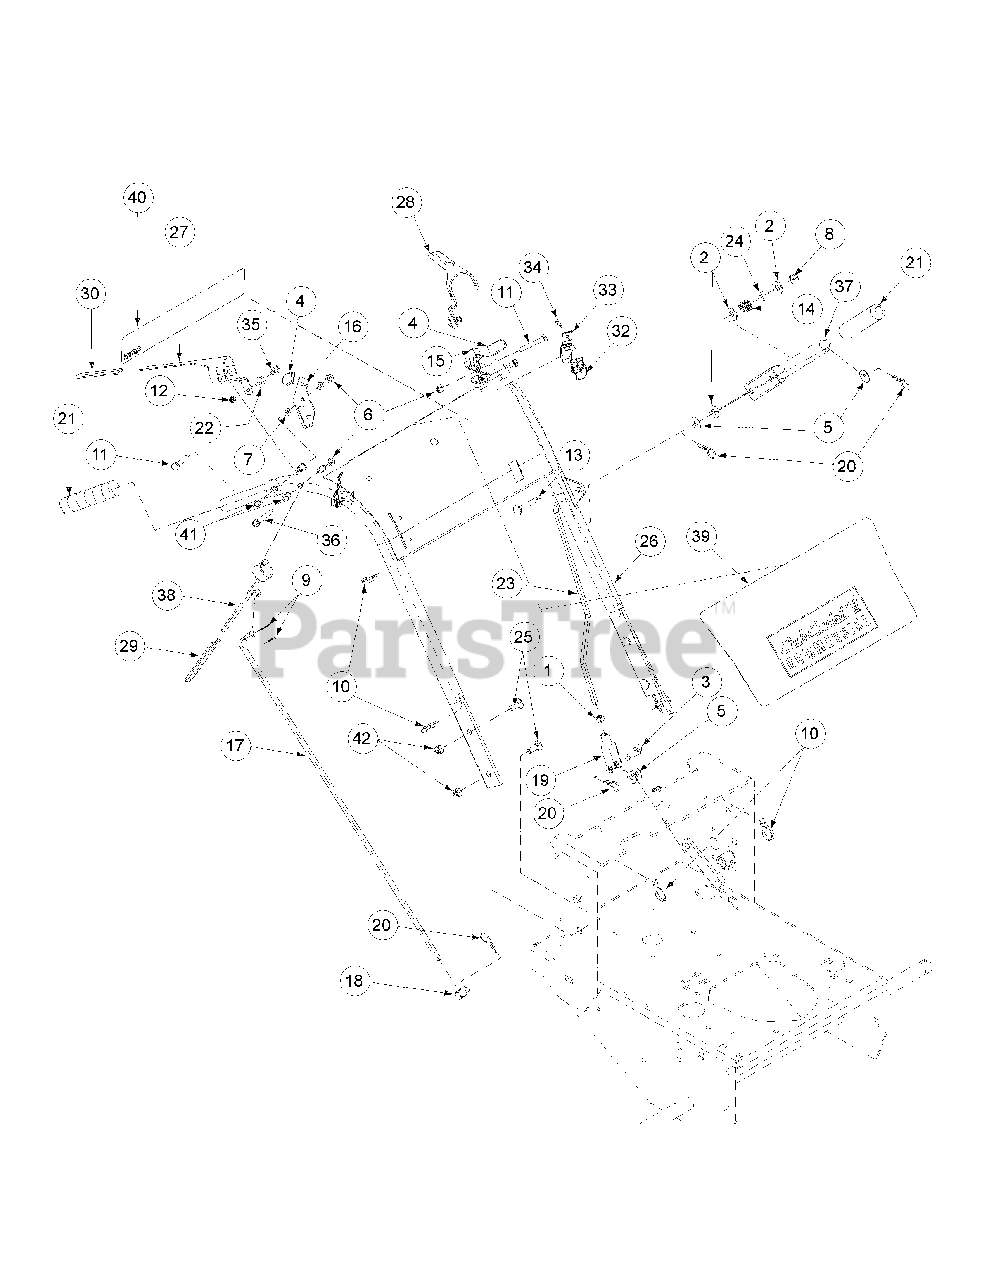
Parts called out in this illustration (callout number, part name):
1	Hex Nut, 3/8-16
2	Flat Washer, 3/8 Zinc
3	Clevis Pin, 3/8 x 1-1/8 Zinc
4	Grip, Neutral Latch, 1.25"
5	Flat Washer, 3/8 Zinc
6	Nylock Nut, 5/16-18
7	Flat Washer, 5/16 Zinc
8	Lock Nut, Nylon Insert, 3/8-16
9	Cotter Pin, 3/32 x 3/4, Zinc
10	Cable Tie, 3/16 x .05 x 7.4
11	Hex Cap Screw, 5/16-18 x 2
12	Lock Nut, Nylon Insert
13	Carriage Bolt, 3/8-16 x 2
14	Spring, .850 OD x 1
15	Neutral Latch, Left Hand
16	Neutral Latch, Right Hand
17	Steering Control Rod
18	Joint Swivel
19	Yoke, 3/8-16 Female
20	Hair Pin 3/8-1/2
21	Handle Grip, Black, 1"
22	Control Rod, Hydro Spacer
23	Blade Clutch Rod
24	Spring Sleeve
25	Carriage Bolt, 3/8-16 x 1.25
26	Handle Assembly
27	Operator Presence Control RH
28	Operator Presence Control LH
29	Control Sleeve, Black
30	Operator Control Sleeve, Yellow
32	Switch Mounting Snap
33	Operator Presence Return Spring
34	Hex Index Washer Screw, 0.500
35	Shoulder Screw, .38 x .412, 1/4-28
36	Hex Cap Screw, 5/16-18, 2.00
37	Blade Clutch Lever
38	Lever Assembly Control
39	Label Commercial Mower Panel
40	Label Commercial Mower Instruction
41	Nylon Bushing
42	Nut, Hex Flange Lock, 3/8-16
